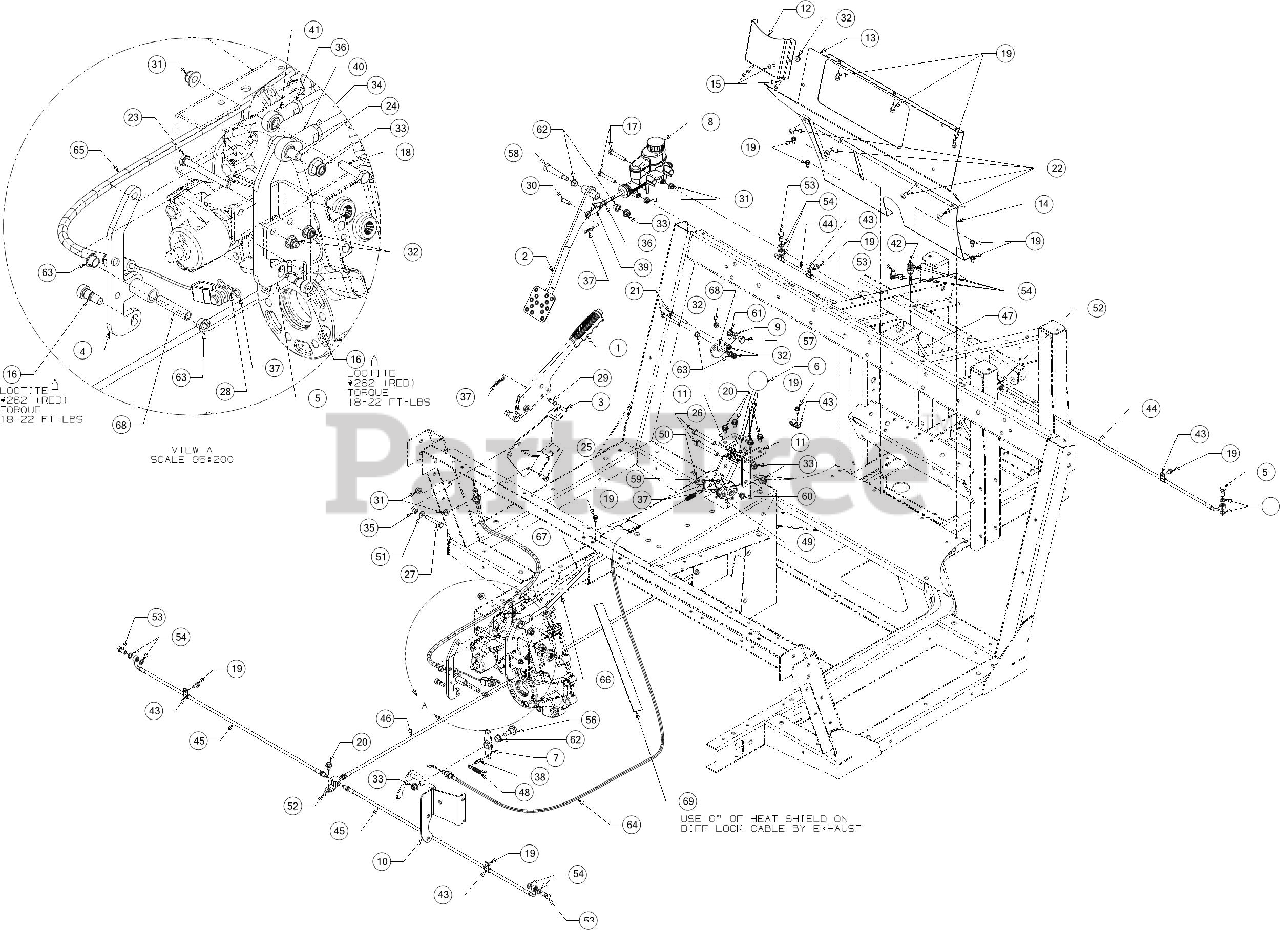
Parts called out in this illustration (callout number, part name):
1	LEVER ASSEMBLY:BRAKE
2	BRAKE PEDAL ASSEMBLY
3	PARK BRAKE BRACKET ASSEMBLY
4	HI-LO SHIFT LEVER ASSEMBLY
5	FNR HI-LO SHIFT LEVER ASSEMBLY
6	HURST SHIFT ASSEMBLY
7	DIFF LOCK LEVER ASSEMBLY
8	MASTER CYLINDER ASSEMBLY
9	OVER CENTER PAWL PLATE
10	DIFFERENTIAL CABLE BRACKET
11	CONSOLE SHAFT MOUNTING
13	EPS UPPER DASH PANEL
14	EPS LOWER DASH PANEL
15	SCREW 1/4-20 x 0.750
16	SHOULDER SCREW .372 x .375 x 5/16-18
17	SCREW-HEAD PATCH GR5 5/16-18X2"
18	SCREW 5/16-18 x 1.25 GR5
19	SCREW 1/4-20 X.500
20	SCREW 5/16-18 x .500
21	SCREW 1/4-20 x 2.25 GR5
22	SCREW 1/4-14 x .625
23	SCREW 1/4-20 x 2.50 GR5
24	SCREW 3/8-16 x 1.25 GR5
25	SCREW 5/16-18 x .75 GR5
26	SCREW 3/8-16 x 2.75 GR5
27	SCREW 5/16-18 x 2.0 GR5
28	CLEVIS PIN .25 x 1.00
29	CLEVIS PIN 5/16 x 3/4
30	CLEVIS PIN .312 x 1.0
31	FLANGE LOCK NUT 5/16-18
32	FLANGE LOCK NUT
34	HEX JAM NUT 3/8X24
35	HEX NUT
36	HEX JAM NUT 5/16-24 GR 5
37	BOW TIE COTTER PIN 1/4-5/16
39	ADJUSTABLE ROD END
40	ROD END 3/8 ID
41	ROD END 5/16 ID
42	BRAKE SWITCH
43	HOSE CLAMP
44	FRONT BRAKE HOSE
45	REAR BRAKE HOSE
46	BRAKE MASTER CYLINDER HOSE (REAR)
47	BRAKE MASTER CYLINDER HOSE (FRONT)
49	FLAT WASHER
50	FLAT WASHER
51	FLAT WASHER
52	TEE FITTING
53	BANJO FITTING
54	BANJO FITTING
56	SHOULDER BOLT .50X.434 EXP
57	SHOULDER SCREW .375X.380:1/4-20
58	SHOULDER SCREW .50 x 2.23 3/8-16
59	FLANGE BEARING
60	FLANGE BEARING
61	BUSHING .380 ID
62	NYLINER BEARING
63	FLANGE BEARING
64	DIFF LOCK CONTROL CABLE
65	PARK CONTROL CABLE
66	F-N-R SHIFT LINK
67	HI/LO SHIFT LINK
68	DIFF LOCK PIVOT SPACER
69	HEAT SHIELD
